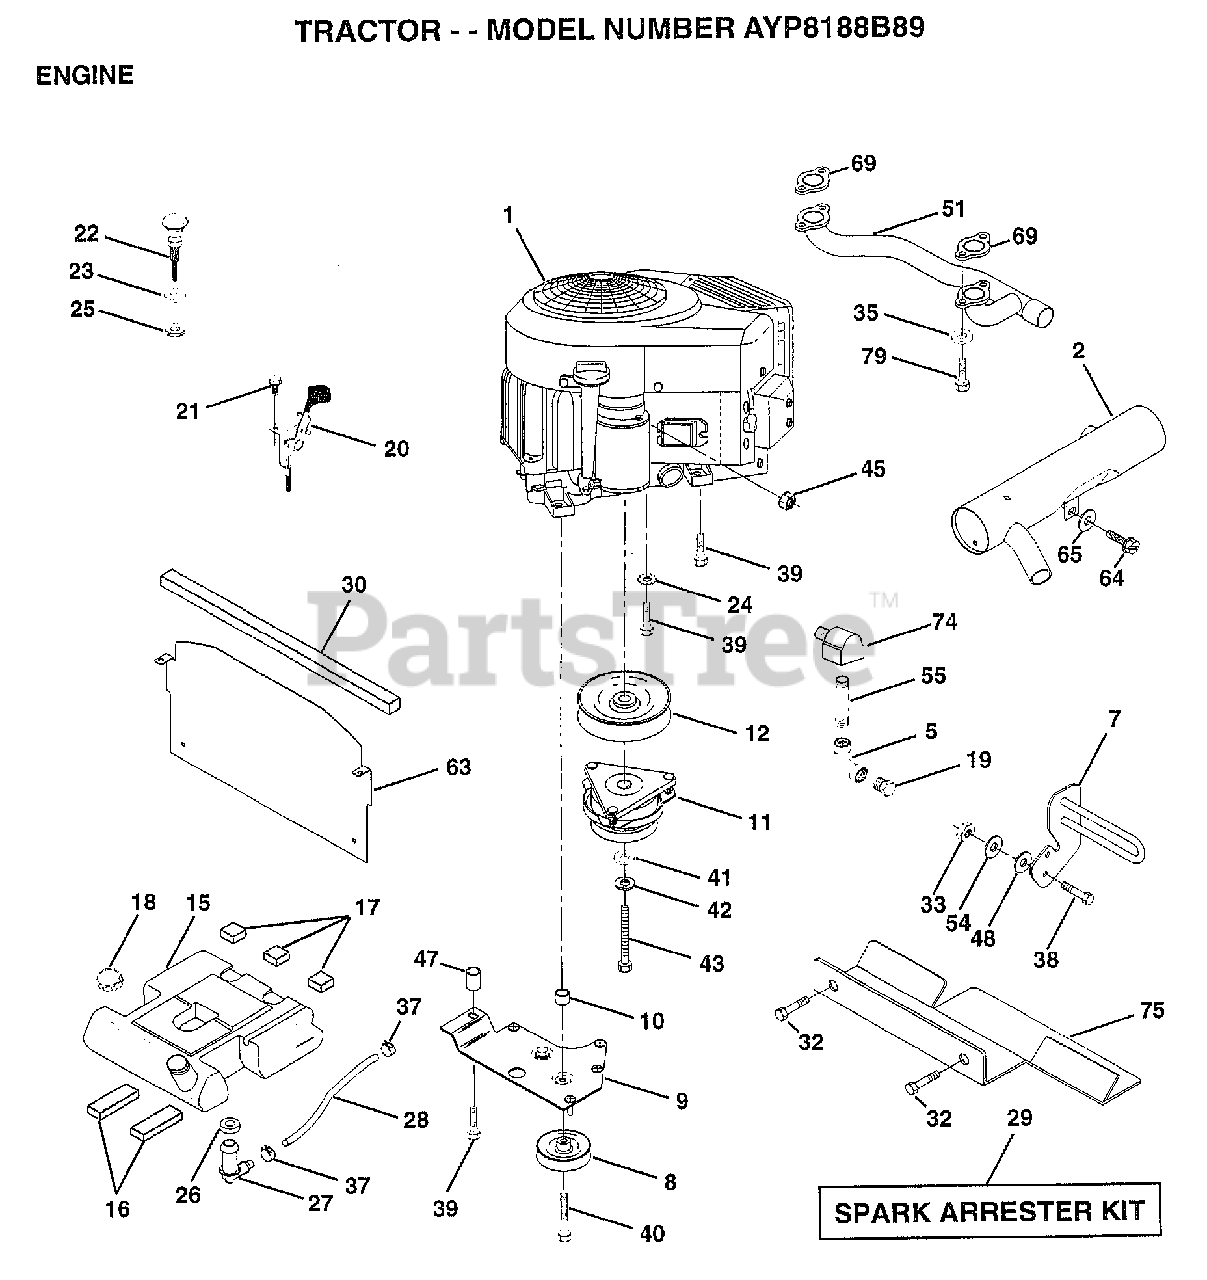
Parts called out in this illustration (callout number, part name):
2	MUFFLER SIDE1-1/8
4	PIPE NIPPLE LT
5	ELBOW
7	GUARD.MUFFLER.ASM
9	KEEPER ASM BELT
10	BUSHING.
12	PULLEY.ENG.CLUTCH
15	TANK FUEL REAR
16	PAD IDLER TI
17	PAD-SPACER LT
18	CAP ASM FUEL
19	PLUG T
21	SCREW LT
22	CHOKE CONTROL
23	WASHER
24	LOCKWASHER
25	"NUT,KEPS 3/8-24IM"
26	BUSHING OUTLET T
27	STEM.TANK.FUEL
29	SPARK ARREST KIT
30	FOAM-STRIP LT
32	SCREW LT
33	NUT
35	LOCKWASHER
37	HOSE CLAMP
38	"BOLT,HEX"
39	SCREW.3/8-16X2.25
40	SCREW.TT.3/8-16X4
41	WASHER
42	LOCKWASHER
43	BOLT.7/16-20X4.25
45	NUT
48	WASHER T
51	PIPE.MANIFOLD
54	WASHER
63	HEAT.SHIELD.VGT.
64	SCREW
65	WASHER
69	GASKET MUFFLER
74	ELBOW STREET BASS
75	SHIELD.HEAT.INTEK.VGT
79	SCREW
